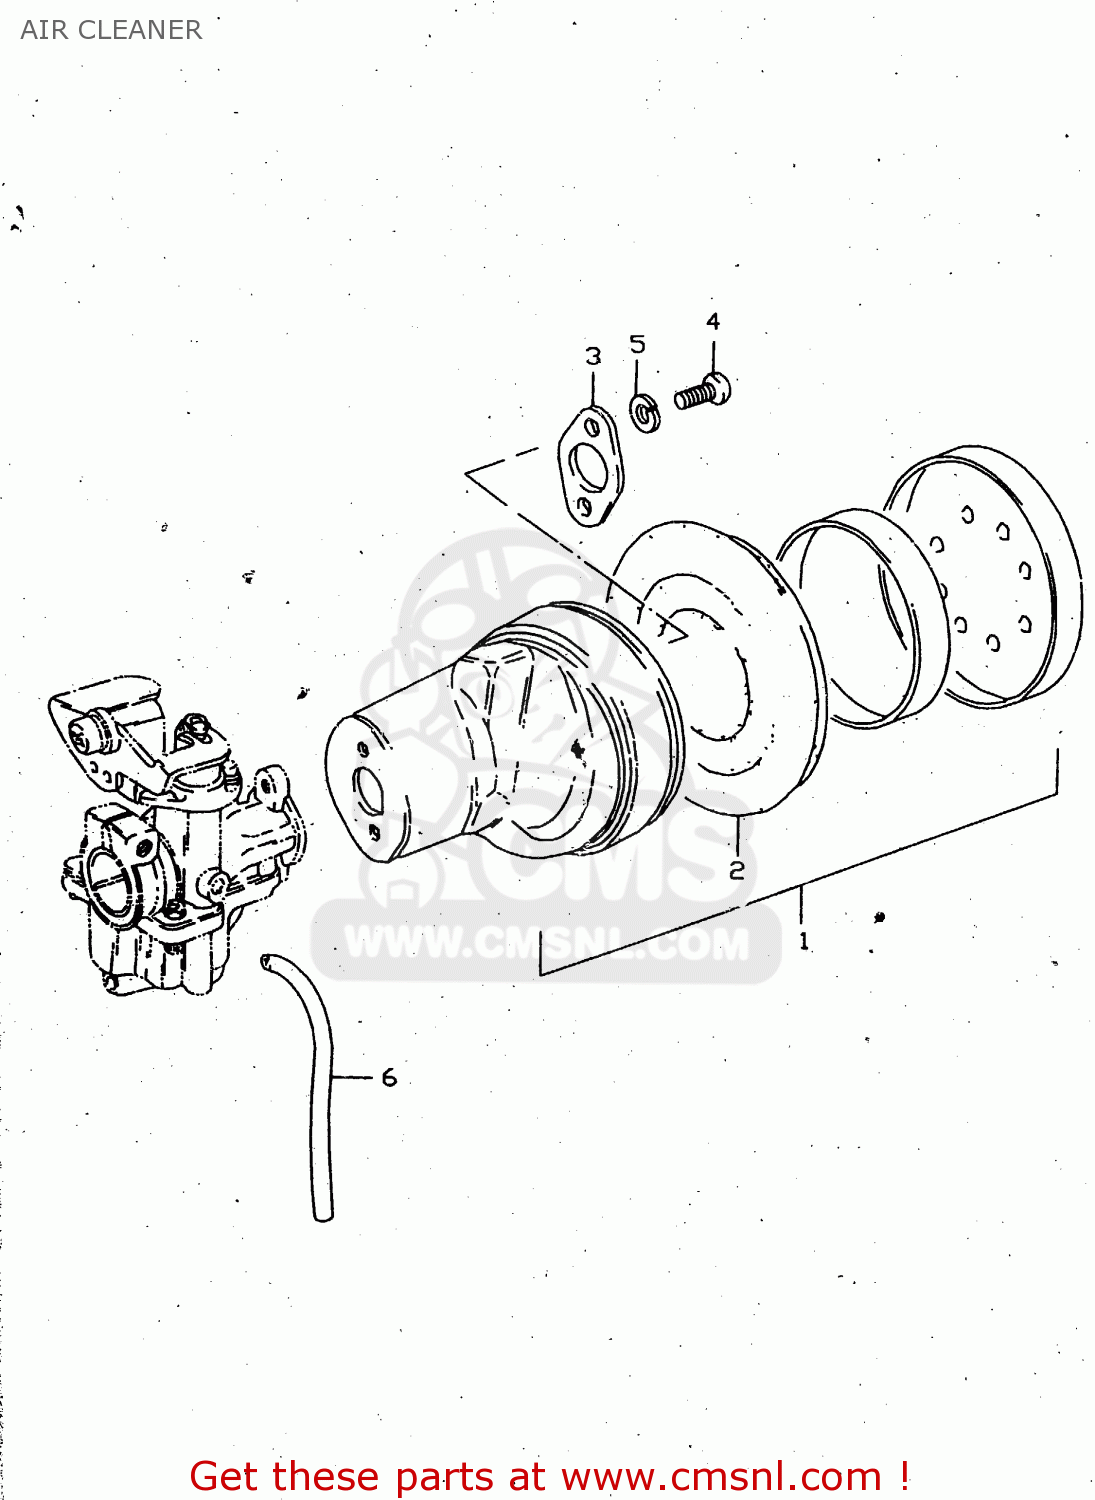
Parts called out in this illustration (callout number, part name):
1	CLEANER ASSY,AIR
2	FILTER,AIR CLEANER
3	PLATE,AIR CLEANER
4	SCREW
5	LOCK,WASHER
6	HOSE(3X5X600)
